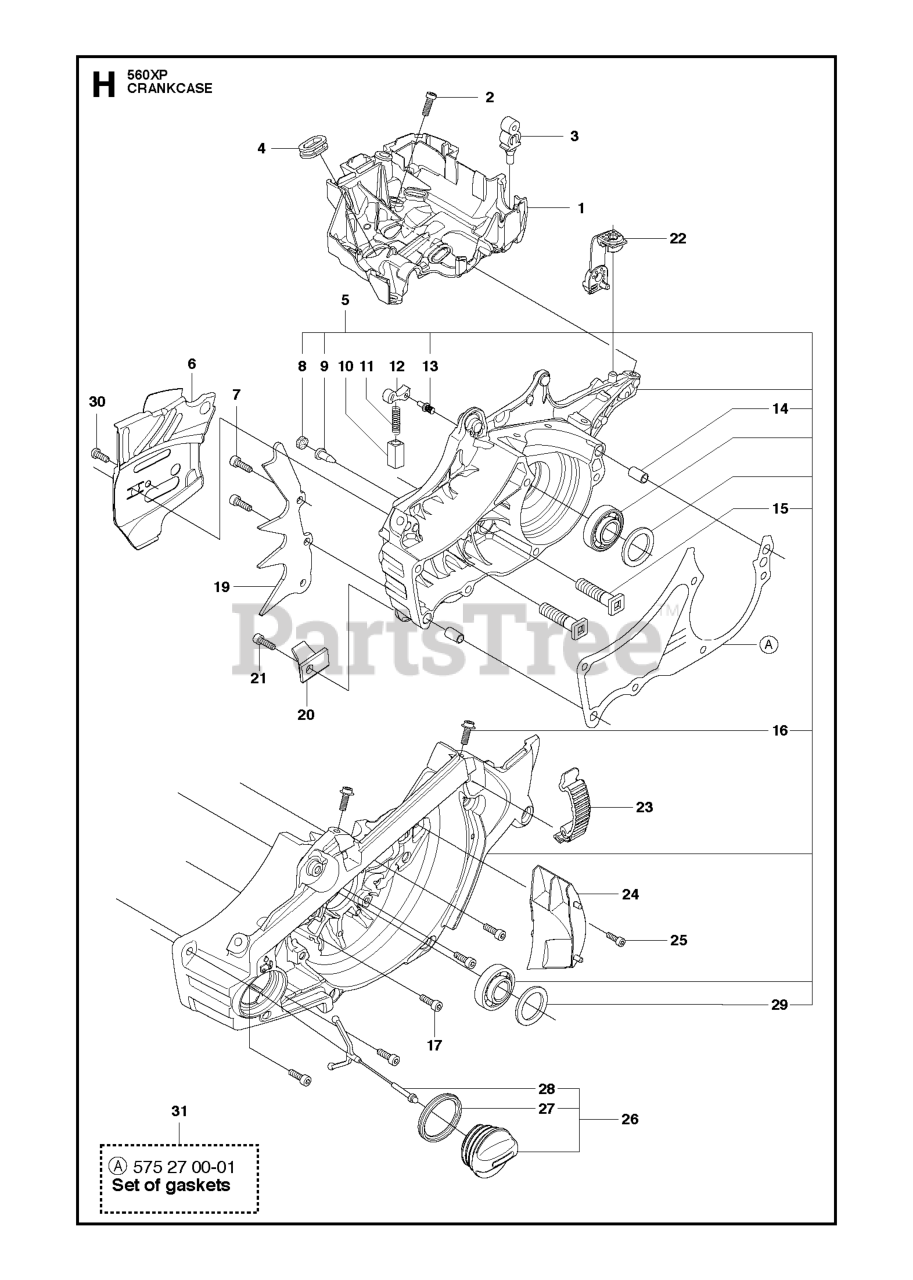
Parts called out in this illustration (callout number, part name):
1	CARBURETTOR AREA BASE
3	SUPPORT
5	CRANKCASE ASSY
6	CHAIN GUIDE PLATE
7	SCREW MC6S 5X16
8	PLUG
9	VALVE-CHECK (DUCKBILL)
11	LOCK SPRING
13	PIN
14	SLEEVE
15	BAR BOLT
16	SCREW IHSCM
17	SCREW IHSCM
20	CHAIN CATCHER
22	DEFLECTION LIMITER
23	CLIP GRAY
24	AIR NOZZLE
25	SCREW IHSCM
26	TANK CAP
27	SEALING
28	TANK LOCK
29	RADIAL SEAL
31	RP GASKET KIT
